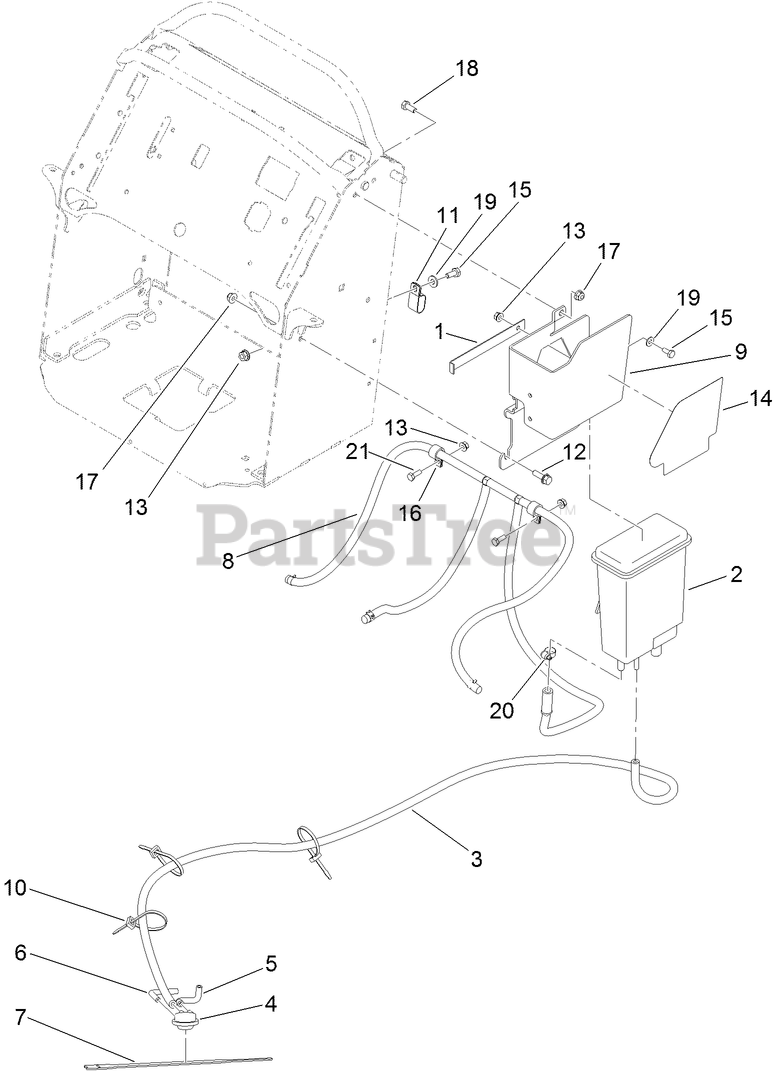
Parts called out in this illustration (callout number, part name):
1	PLATE-LOC
2	CANISTER-CARBON, 1200CC
3	HOSE-FUEL
4	VALVE-CONTROL, VACUUM
5	HOSE-VENT, FORMED
6	HOSE-VENT, FORMED
7	STRAP-VELCRO, CABLE TIE
8	VENT HOSE ASM
9	PLATE- ADAPTER
10	TIE-CABLE
11	CLAMP-TUBE, DOUBLE
12	SCREW-HHF
13	NUT-HHF
14	DECAL-AID, SERVICE
15	SCREW-HH
16	CLAMP-CABLE
17	NUT-HF, NI
18	SCREW-HH
19	WASHER-FLAT
20	CLAMP-WORM
21	SCREW-HH
